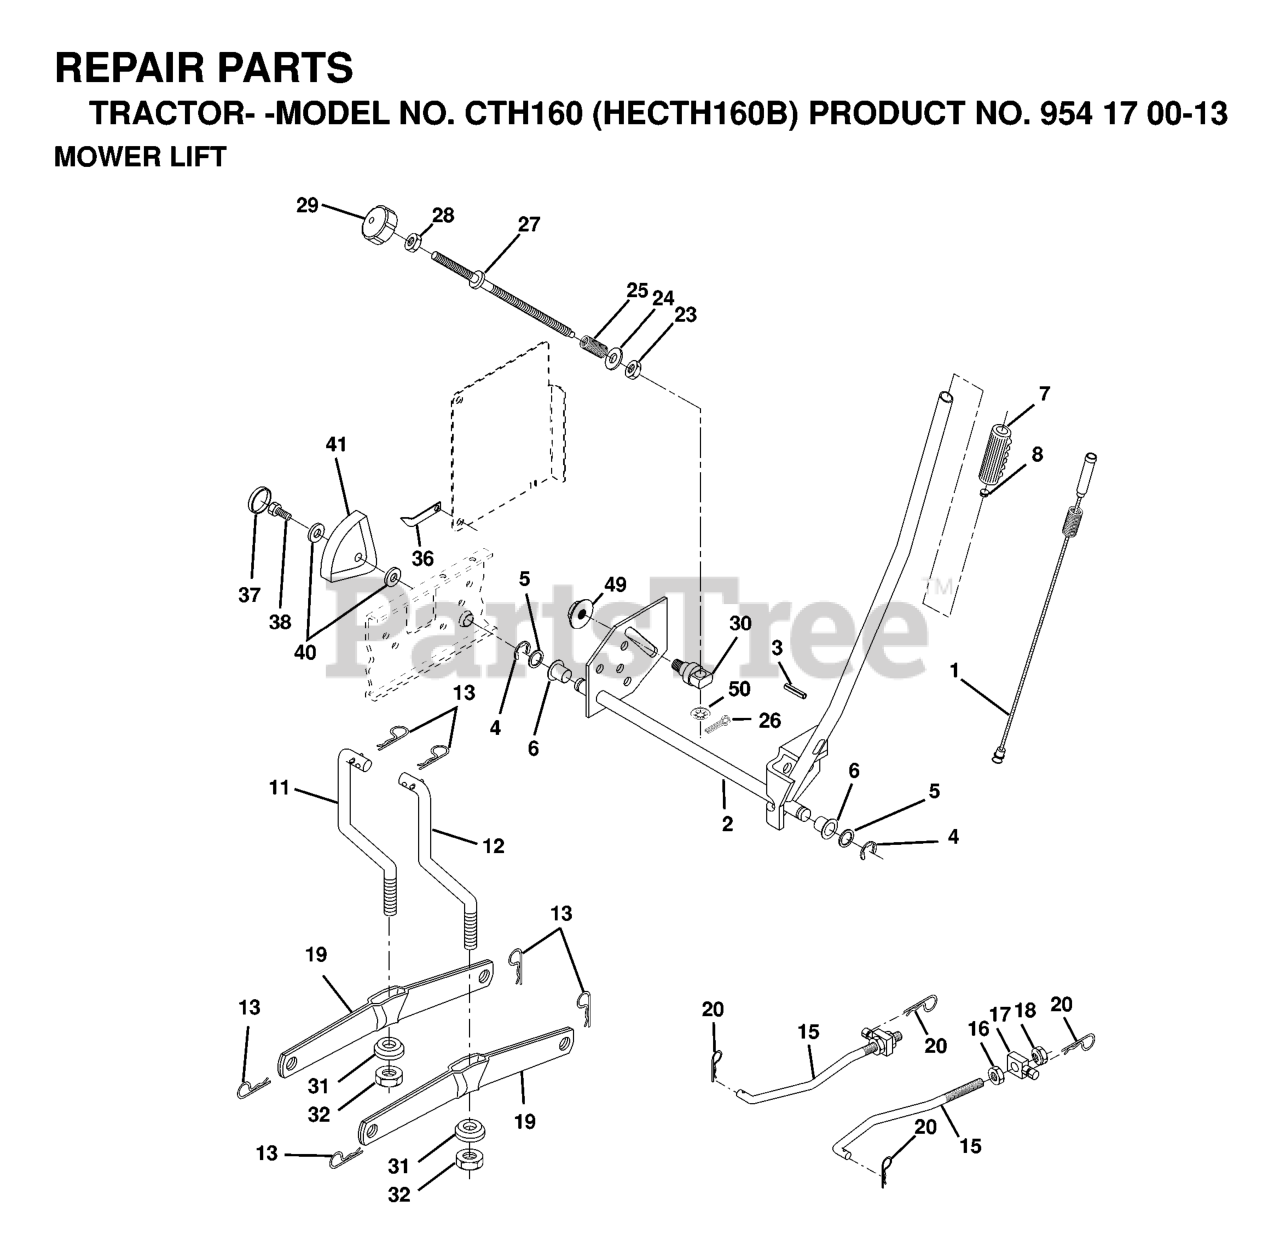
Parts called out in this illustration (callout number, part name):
1	WIRE ASM INNER W/ PLUNGER LT
2	SHAFT ASM R HANDLE
3	PIN GROOVE.
4	RETAINING RING LT
6	BEARING.NYLON
7	GRIP HANDLE
8	PLUNGER BUT KIT
11	LINK
12	LINK
13	RETAINER-SPRNG RB
15	FRONT LINK
16	NUT.HEX.JAM.1/2-13
17	TRUNION
18	NUT LTV
19	ARM.REAR.SUSPENSION
20	SPRING RETAINER
25	SPRING**
26	COTTER PIN
27	ROD ADJ LIFT
28	NUT
29	KNOB INF 3/8-16
31	BEARING PIVOT
32	NUT CROWNLOCK 3/8-24
36	POINTER, HEIGHT INDICATOR(2 2)
38	SCREW.THDROL.5/16-18X3/4.TTY
41	HEIGHT INDICATOR
49	NUT
50	NUT PUSH M
